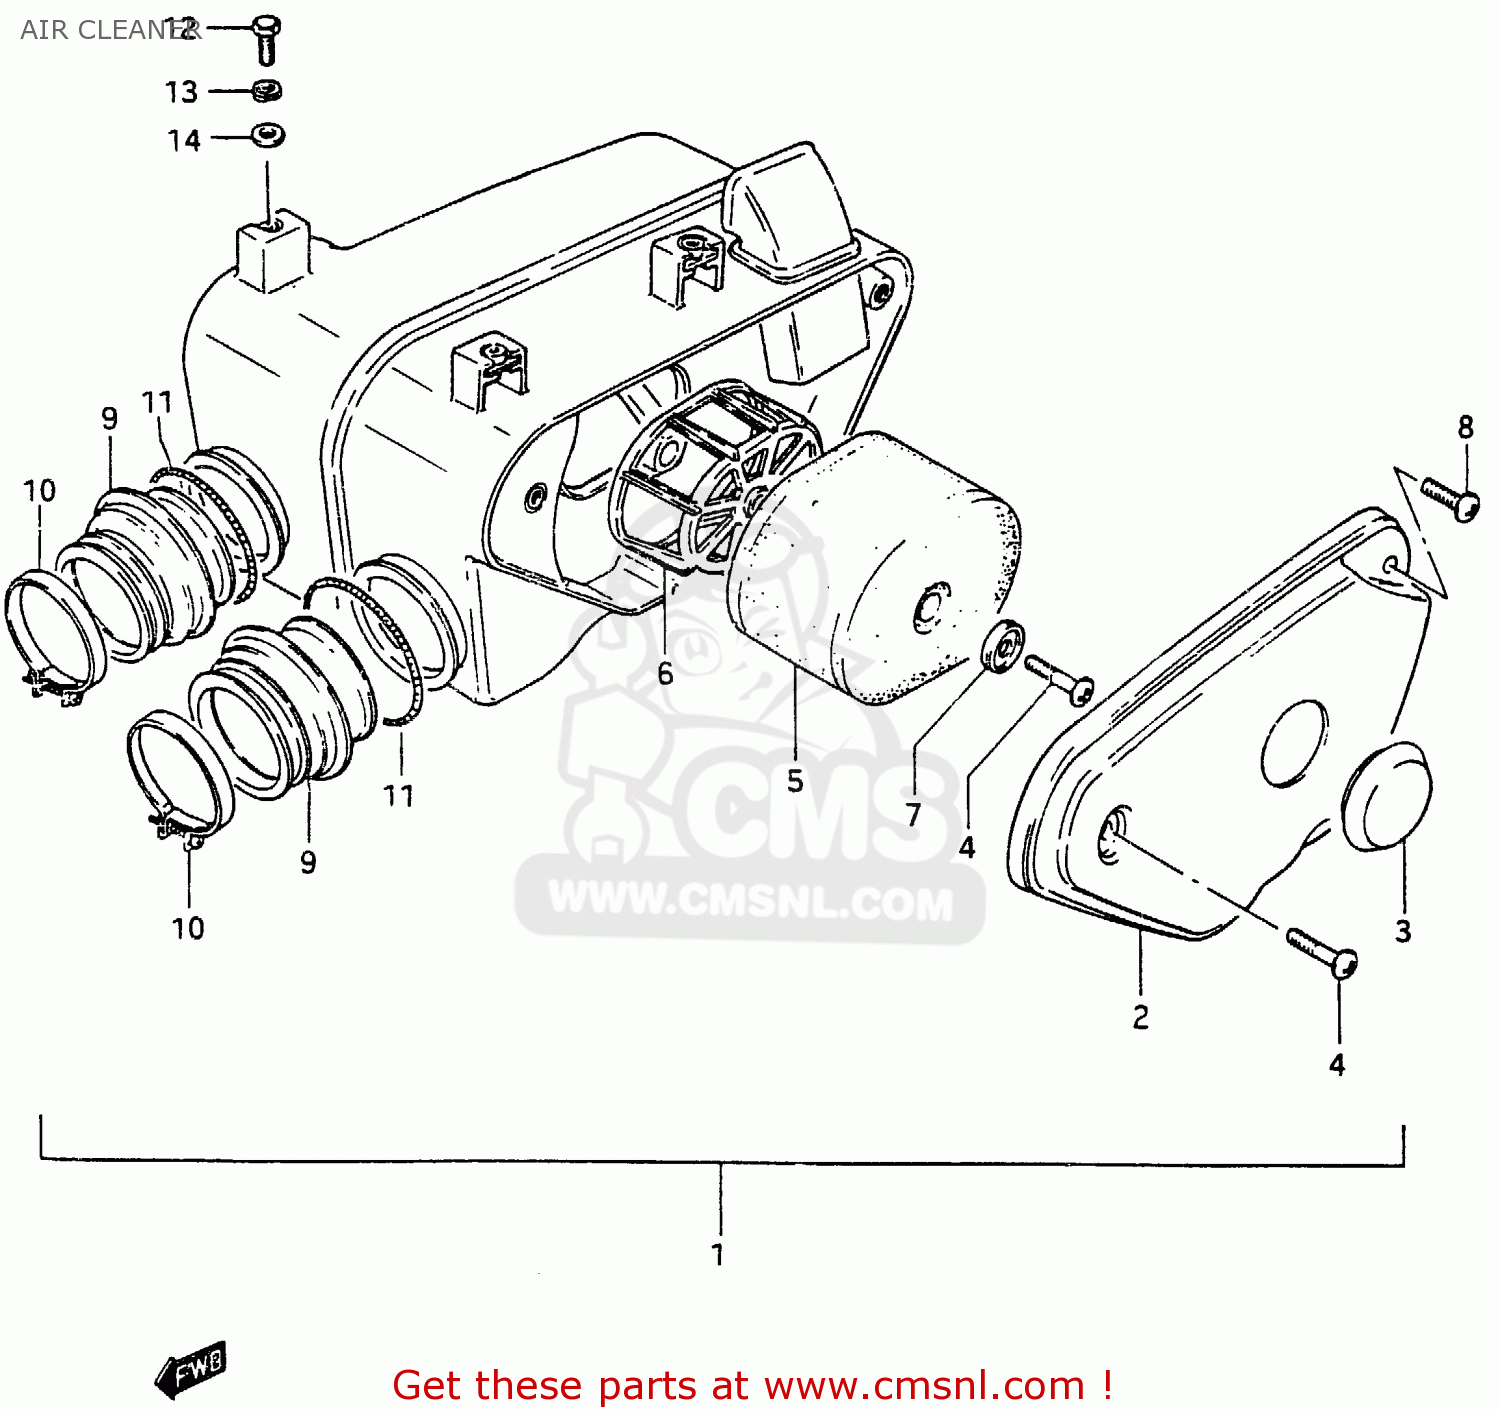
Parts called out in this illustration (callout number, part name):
1	CLEANER ASSY, AIR
2	CAP, AIR CLEANER
3	CAP, RUBBER
4	SCREW
5	FILTER,AIR CLEANER
6	HOLDER,AIR CLEANER
7	WASHER,FILTER HOLDER
8	SCREW
9	TUBE,AIR CLEANER OUTLET
10	CLAMP
11	SPRING,AIR CLEANER SIDE
12	BOLT, UPPER
13	WASHER,LOCK
14	WASHER
